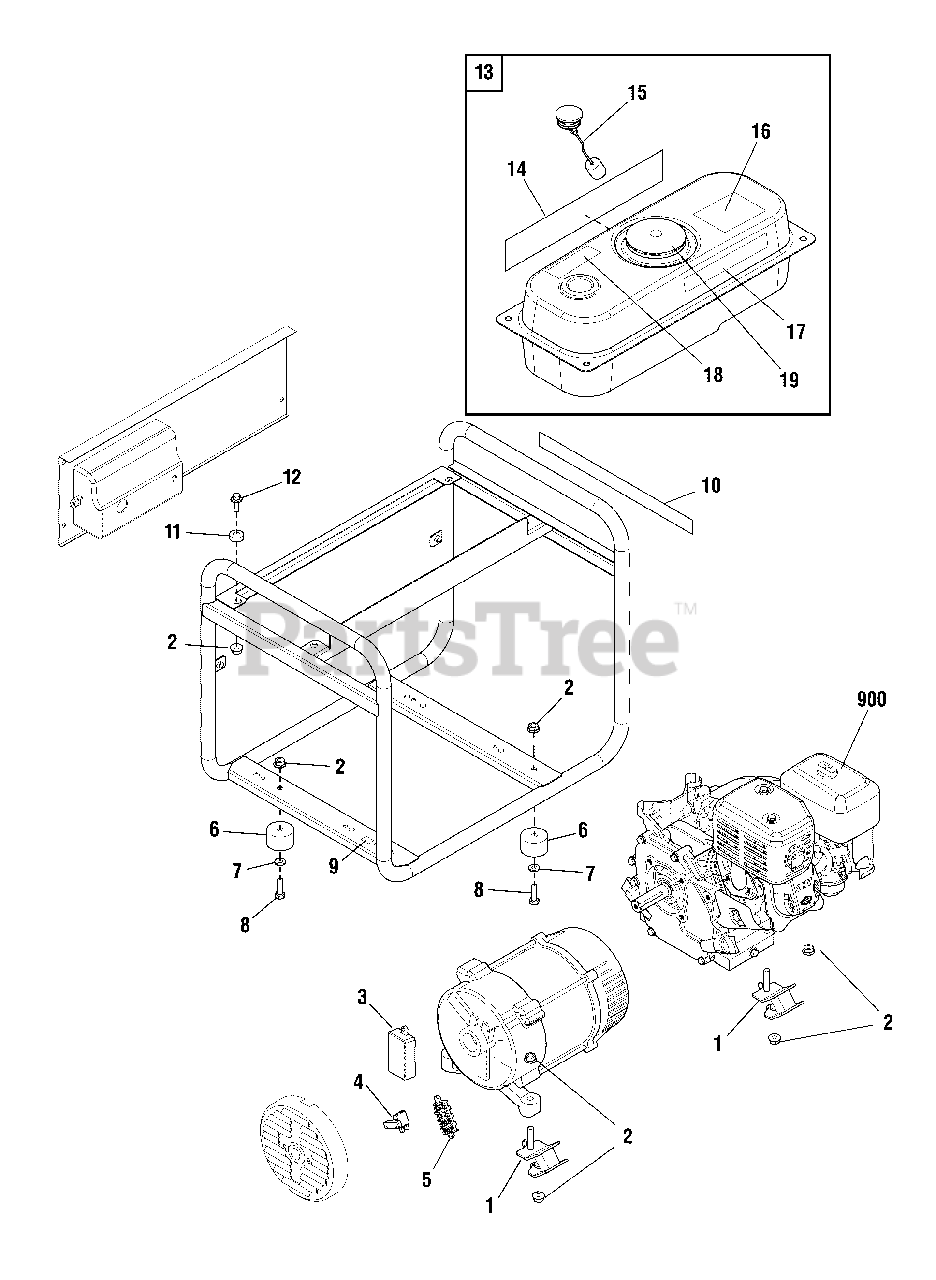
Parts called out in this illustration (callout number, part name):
1	MOUNT, Vibration
2	* NUT, Flange, M8
3	REGULATOR, Voltage
5	BLOCK, Junction
6	MOUNT, Vibration
7	* WASHER, M8
8	* BOLT, M8 x 22
12	* BOLT, M8 x 20
900	** ENGINE
